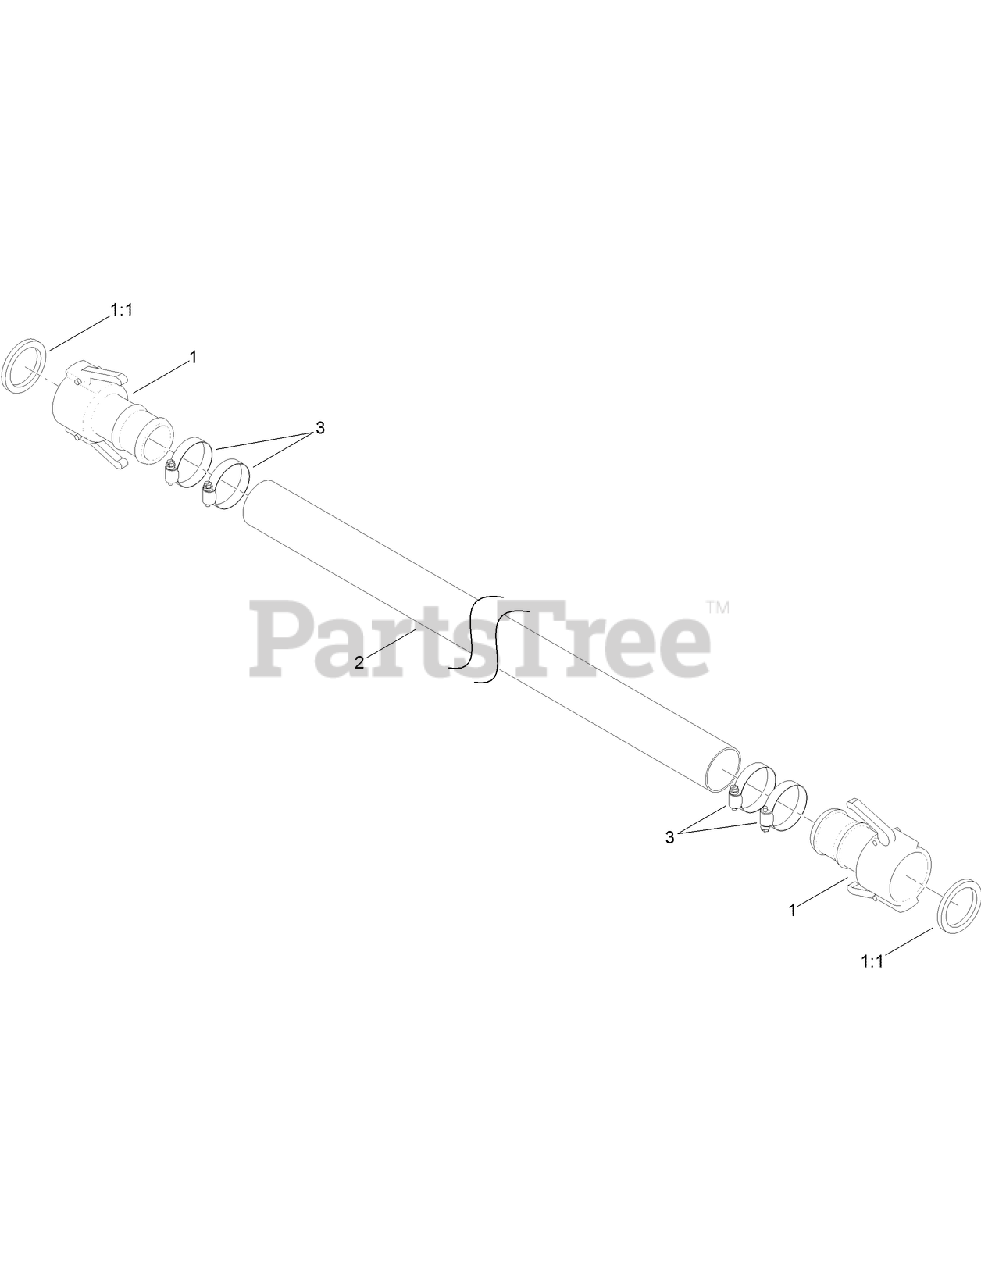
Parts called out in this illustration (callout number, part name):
1	COUPLER-LOCK, CAM
1:1	GASKET
2	HOSE-DISCHARGE
3	CLAMP-HOSE
